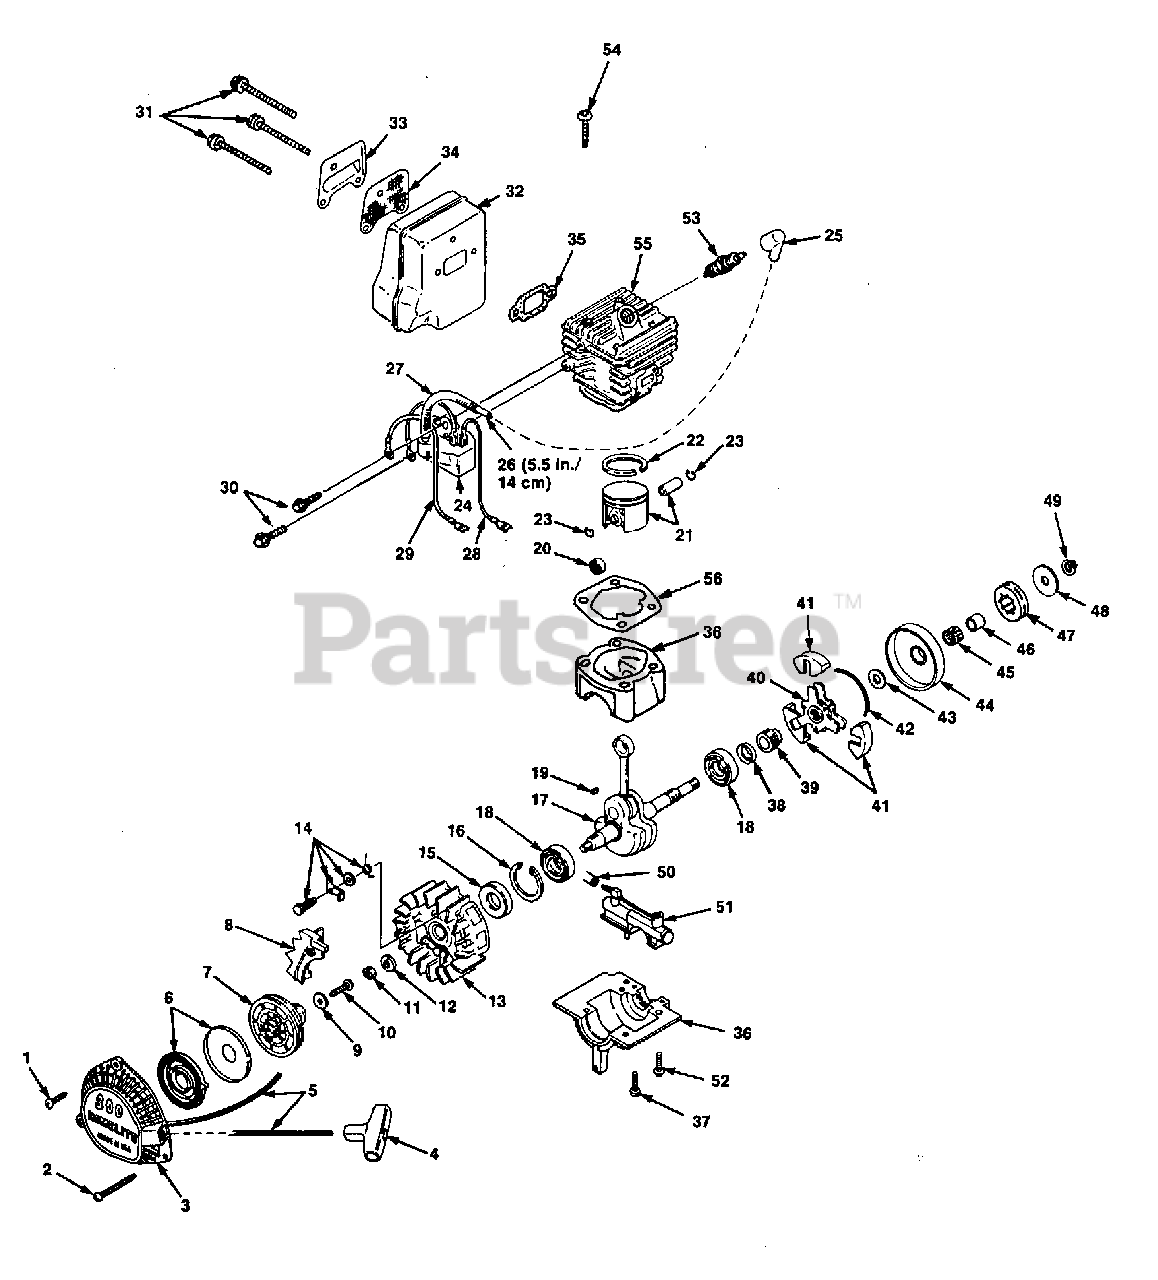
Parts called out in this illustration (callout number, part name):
1	SCREW- (8-16 x 1/2")
2	SCREW- (8-16 x 2 1/4")
3	STARTER HOUSING w/Decal
4	GRIP-Starter
5	ROPE
6	SPRING & CONTAINER
8	HOUSING- Starter side
9	WASHER- Retainer
10	SCREW- Thd. forming (10-24 x 5/8")
11	NUT-Jam
12	WASHER- Lock (3/8")
13	ROTOR & STARTER PAWL ASSY.
14	STARTER PAWL
15	SEAL- Shaft
16	RING- Retaining
17	CRANKSHAFT ASSY.
18	BEARING- Ball
19	KEY- Woodruff
20	BEARING- Roller
21	PISTON & PIN ASSY.
22	RING- Piston
23	RING- Retainer
24	MODULE- Ignition
25	BOOT- Spark plug
26	LEAD- Hi Tension
27	INSULATOR- Lead
28	WIRE- Ignition
29	WIRE- Ground
30	SCREW- (10-24 x 7/8")
31	SCREW- Sems (10-24)
32	BODY- Muffler
33	COVER- Exhaust
34	SCREEN- Spark arrestor
35	GASKET- Muffler
36	CRANKCASE ASSY.
37	SCREWS- (12-24 x 7/8")
38	SEAL- Crankshaft
39	WORM- Left hand
40	CLUTCH- Spider
41	SHOE- Clutch
42	SPRING- Clutch
43	WASHER- Thrust (Inner)
44	SPLINE & DRUM
45	BEARING- Needle
46	RACE- Inner
47	SPROCKET- (.325 x 8 tooth)
49	NUT- Lock hex (3/8-24)
50	LINE- Oil
51	PUMP- Oil
52	SCREW- Oil pump (8-32 x 5/8")
53	PLUG- Spark (RCJ6Y)
54	SCREW- Pan Hd.
55	CYLINDER & GASKET
